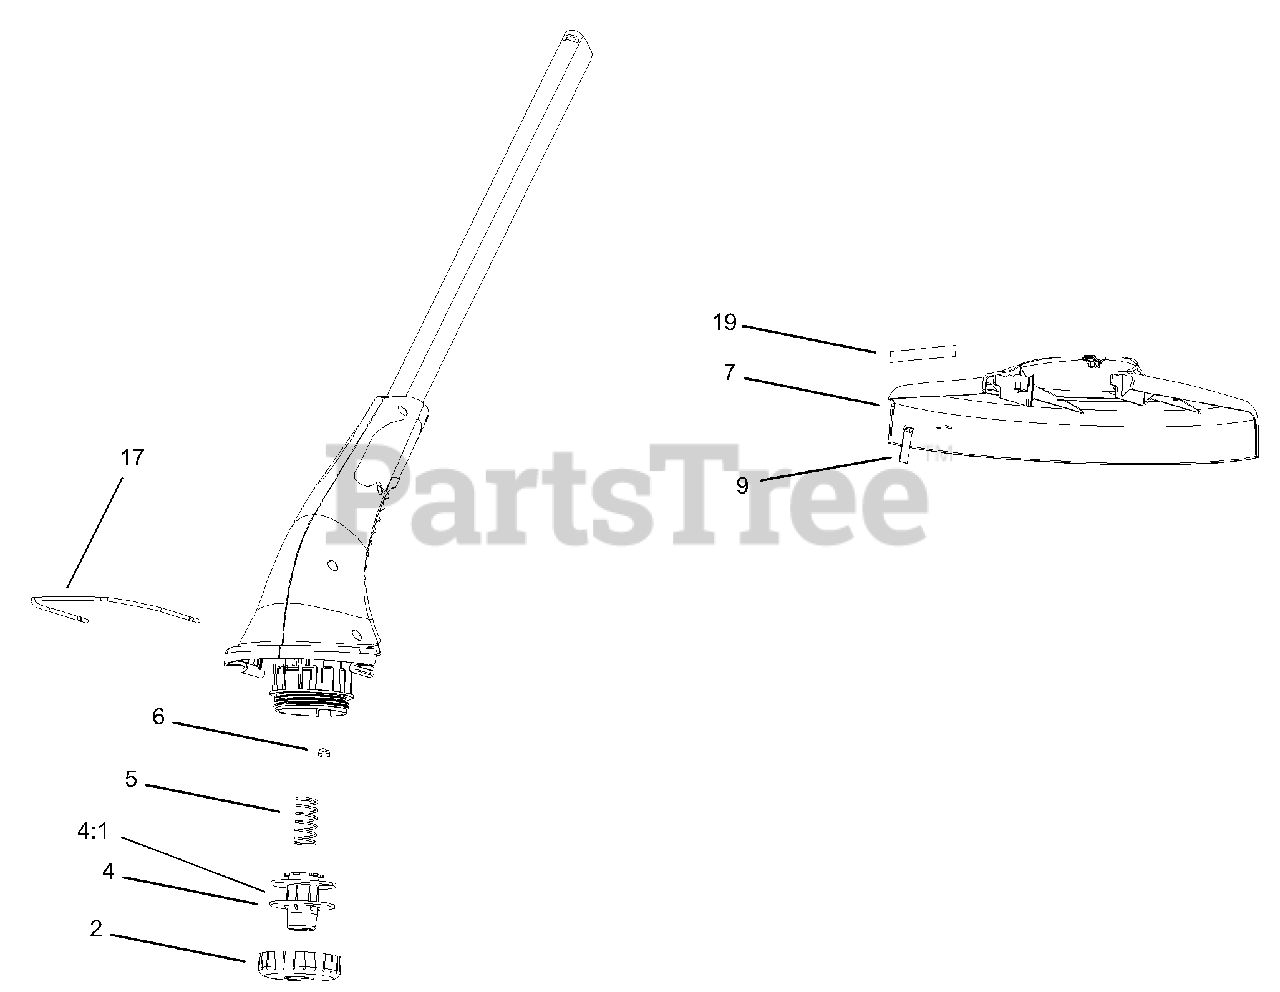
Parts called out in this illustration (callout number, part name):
4	.065 Spool ASM
4:1	Spool-Large
5	Spring-Extension
6	Eyelet-Drum
7	Shield-Variable Cut
9	Blade-Variable Cut
17	Guide-Edge
19	Decal-Shield, Length
